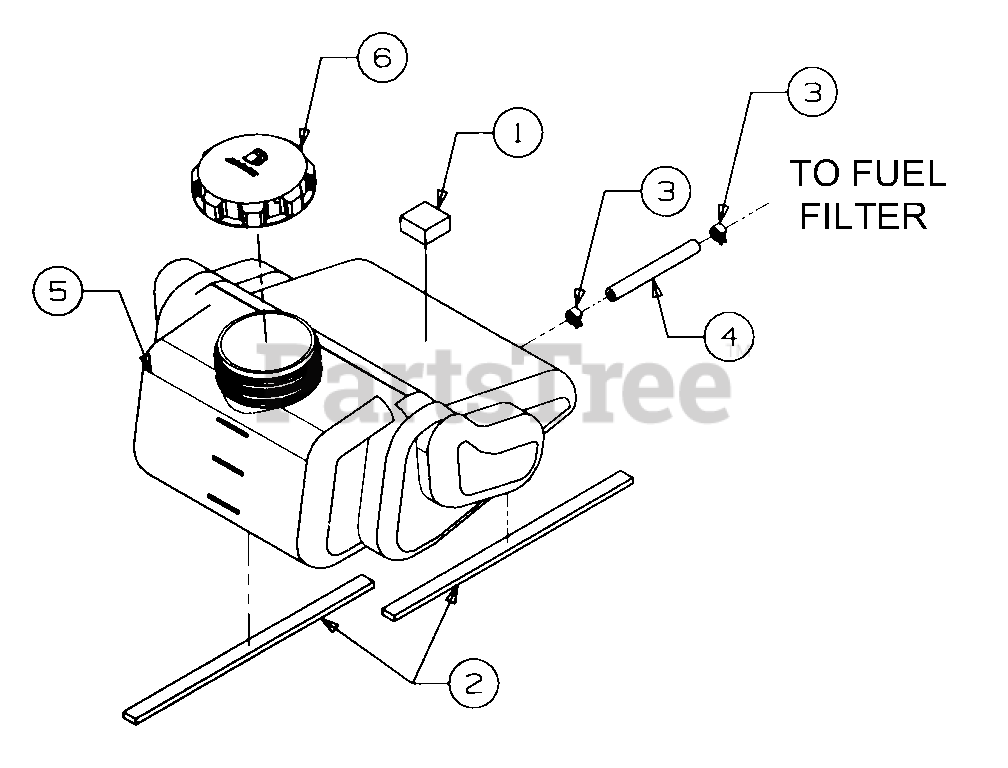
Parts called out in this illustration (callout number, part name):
1	Foam, 1.25 Sq x .62 Thk
2	Tape, Foam, .625 Wide x .25 Thk
3	Clamp, Hose
4	Line, Fuel, 72" (Shipped In 10ft Length)
5	Tank, Fuel
6	Cap, Fuel
